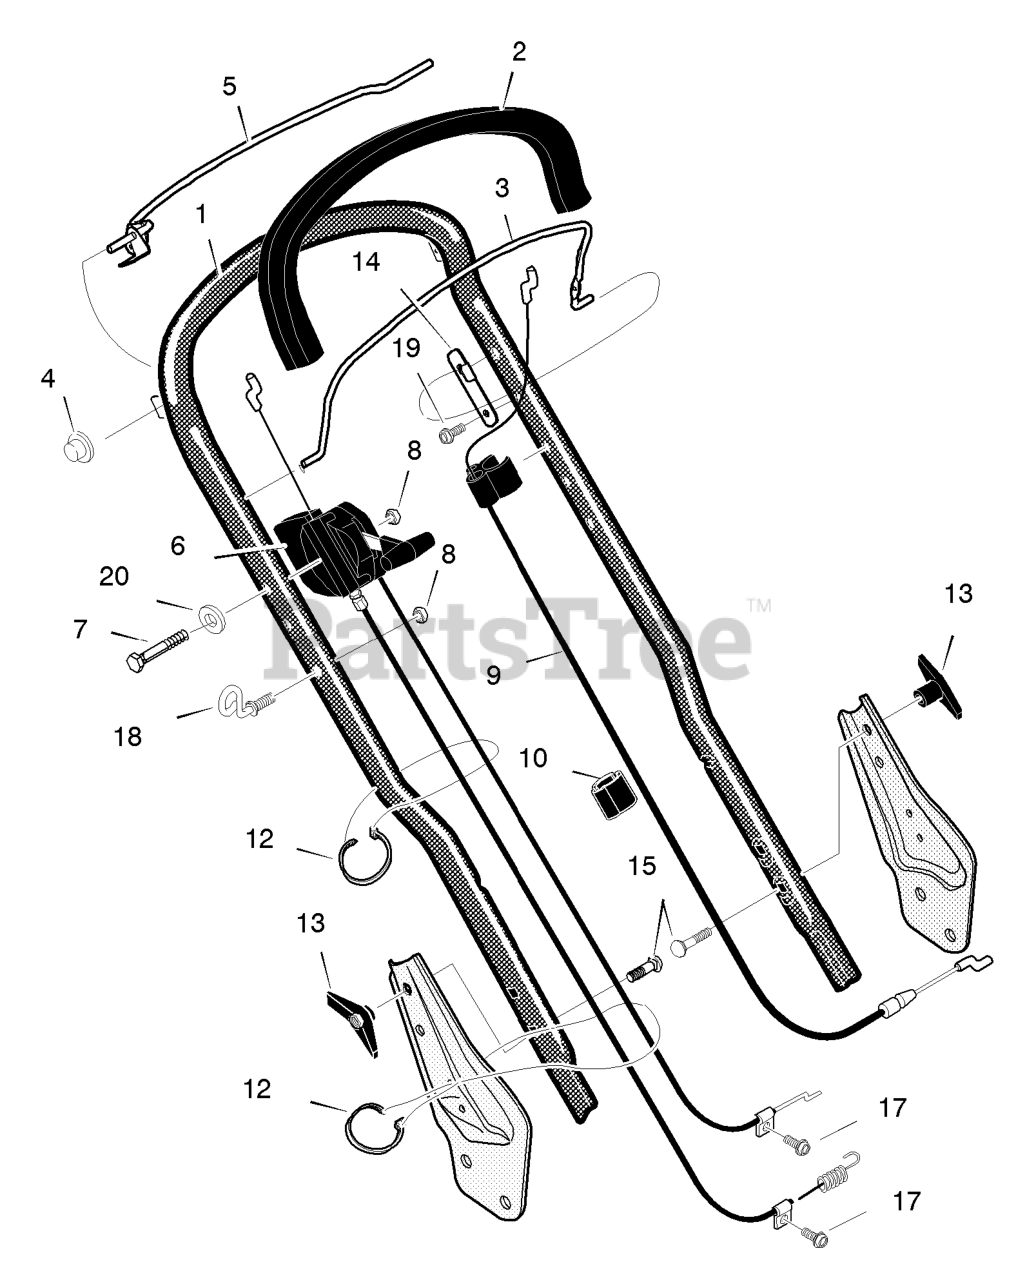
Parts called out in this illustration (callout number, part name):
1	HANDLE, UPPER
2	SLEEVE, HANDLE
3	LEVER, STOP
4	PUSH CAP
5	LEVER ASSEMBLY, DRIVE
6	DRIVE CONTROL & CABLE
8	NUT
9	CABLE, STOP
10	CLIP, CABLE
12	STRAP, TIE
13	WINGNUT
14	BRACKET, STOP
15	BOLT, CARRIAGE
18	GUIDE, ROPE
19	SCREW
20	WASHER
